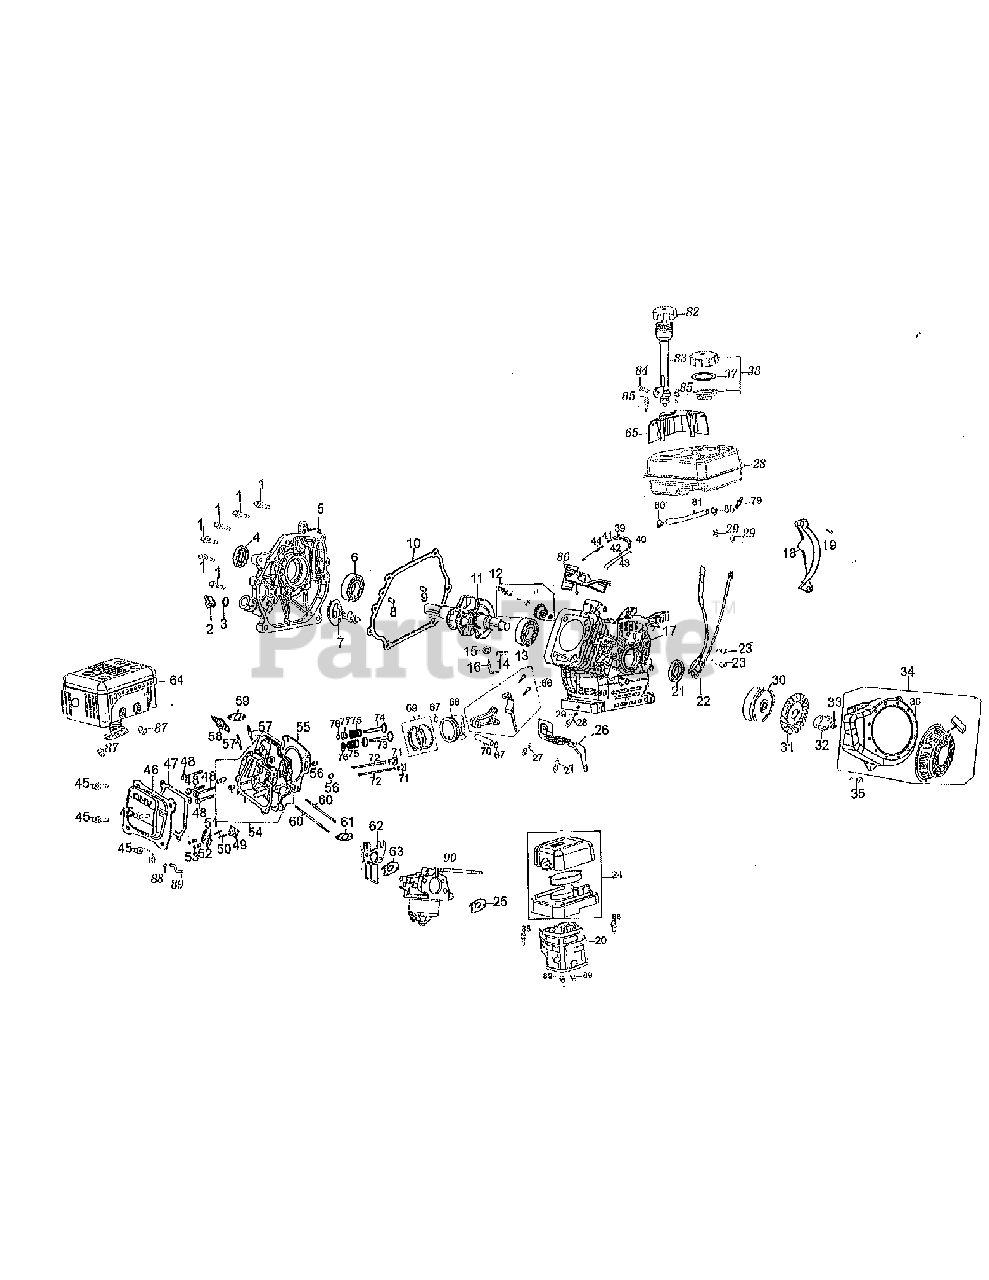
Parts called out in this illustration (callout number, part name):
1	Bolt
2	Oil Fill Plug Assembly
3	O-Ring
4	Oil Seal
5	Left Crankcase Cover
6	Radial Ball Bearing
7	Camshaft Assembly
8	Dowel Pin
9	Dowel Pin
10	Case Cover Packing
11	Crankshaft Complete
12	Governor Kit
13	Radial Ball Bearing
14	Lock Pin
15	O-Ring
16	Governor Arm
17	Crankase Complete
20	Air Filter Heating Pipe Base
21	Oil Seal
22	Ignition Complete
24	Air Filter Housing
24	Air Filter
25	Carburetor Packing
28	Fuel Tank
28	Bolt
29	Nut
30	Flywheel
31	Cooling Fan
34	Recoil Starter Assembly
34	Recoil Spring and Pulley Assembly
38	Fuel Filler Cap Complete
44	Governor Spring
47	Head Cover Gasket
51	Rocker Arm
52	Valve Adjusting Nut
53	Pivot Locking Nut
54	Cylinder Head Complete
55	Cylinder Head Gasket
56	Dowel Pin
57	Stud 8 × 34
58	Spark Plug
59	Muffler Gasket
61	Carburetor Insulator Packing
62	Carburetor Insulator
64	Muffler
65	Dipstick Decoration Cover
66	Connecting Rod Assembly
67	Piston Pin Clip
68	Piston
69	Piston First Ring Set
70	Piston Pin
71	Push Rod Kit
71	Valve Lifter
71	Push Rod
73	Valve Kit
73	Inlet Valve
73	Exhaust Valve
79	Fuel Tank Nipple
81	Fuel Line Kit
82	Dipstick
83	Engine/Dipstick Cover
85	Bolt - M6 X 28 Zinc Coating
90	Carburetor
